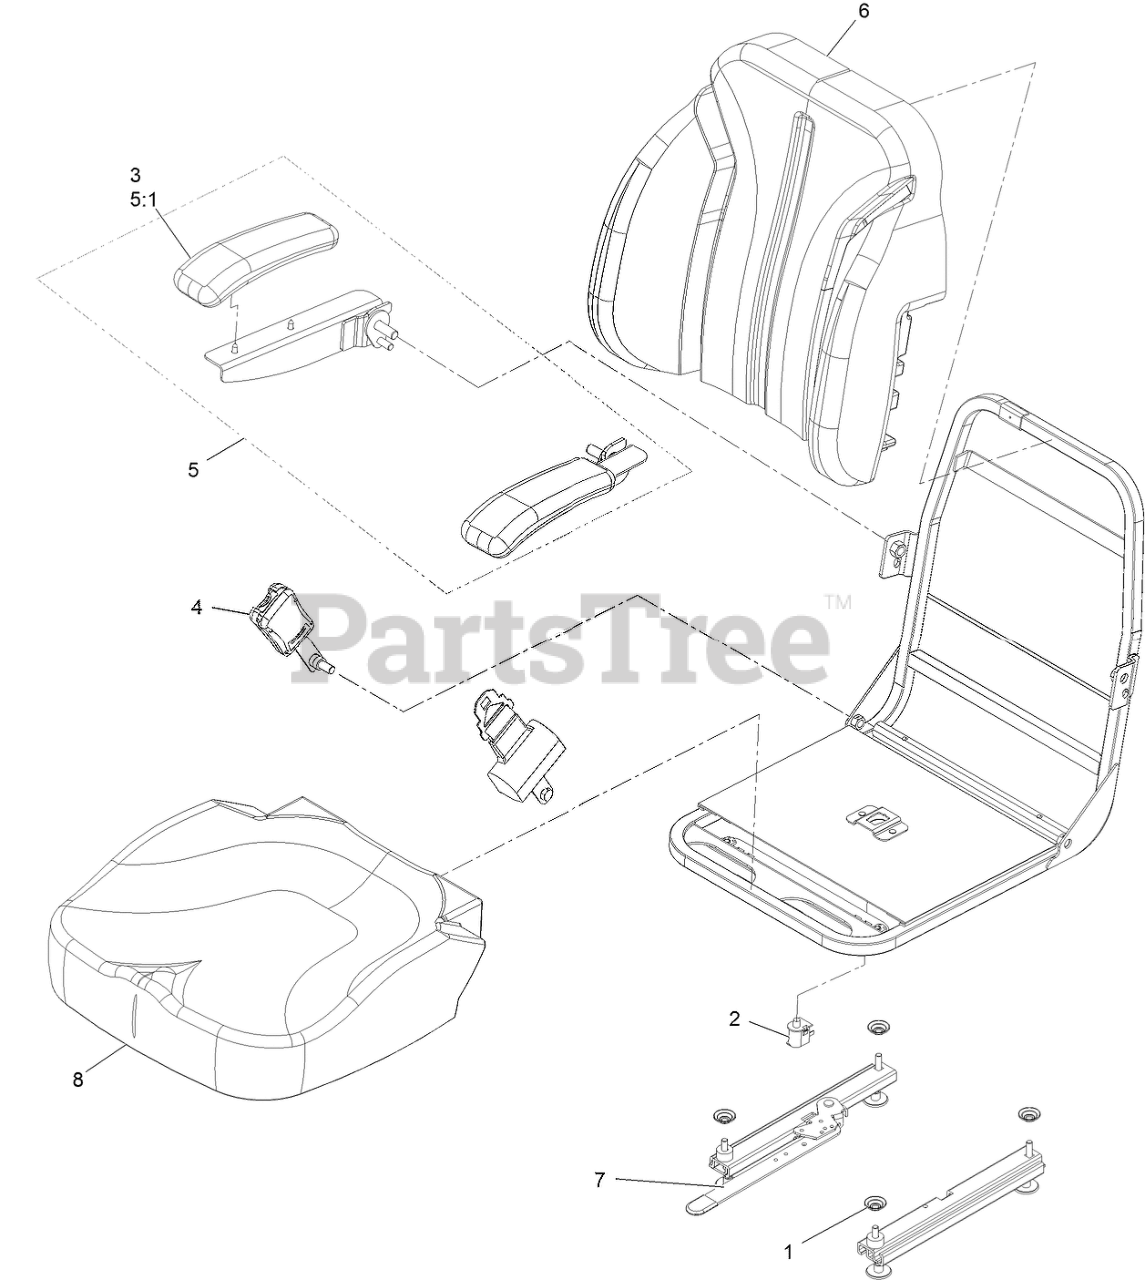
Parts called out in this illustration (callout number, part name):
1	SPACER-MOUNTING
2	SWITCH-BAIL
3	CUSHION-REST, ARM
4	SEAT BELT KIT
5	ARMREST KIT
5:1	CUSHION-REST, ARM
6	COVER-SEAT BACK SVC
7	TRACK-SEAT
8	COVER-SEAT BOTTOM SVC
